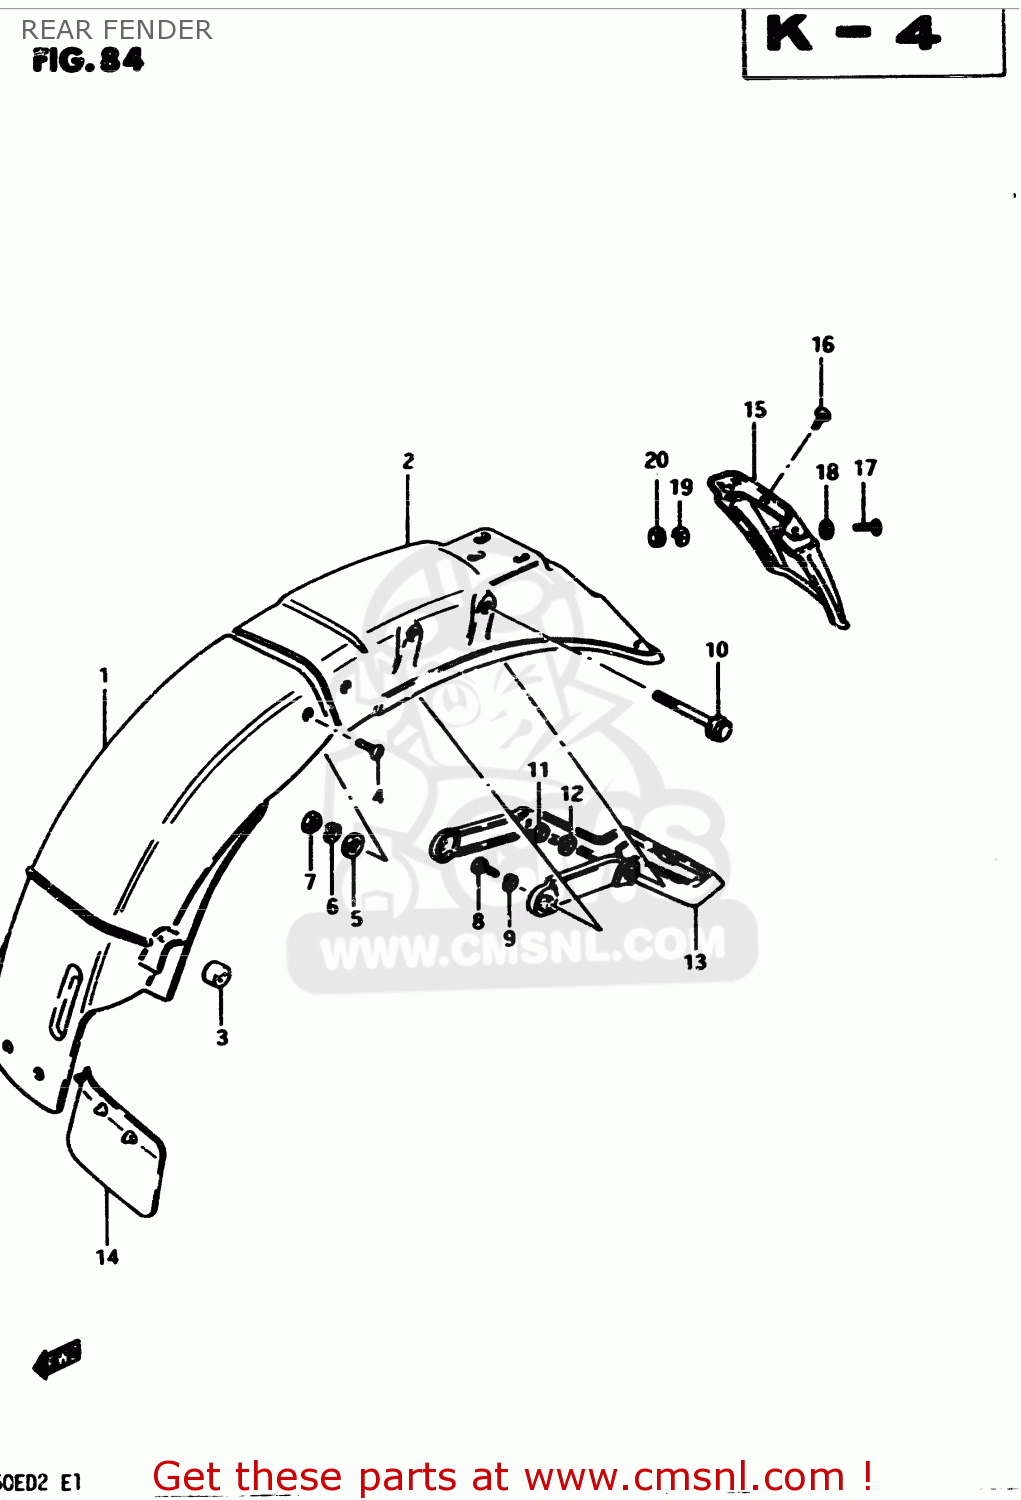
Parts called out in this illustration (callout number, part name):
1	FENDER,REAR
2	BODY,REAR FENDER,REAR
3	CUSHION
4	SCREW
5	WASHER (5.5X16X1.2)
6	LOCK WASHER
7	NUT
8	BOLT, UPPER
9	LOCK WASHER
10	BOLT
11	NUT
12	LOCK WASHER
13	REINFORCEMENT,REAR FENDER
14	GUIDE,RR FENDER MUD
15	EXTENTION, REAR FENDER
16	SCREW 6X12
17	SCREW
18	WASHER(6.5X18X1)
19	LOCK WASHER
20	NUT
